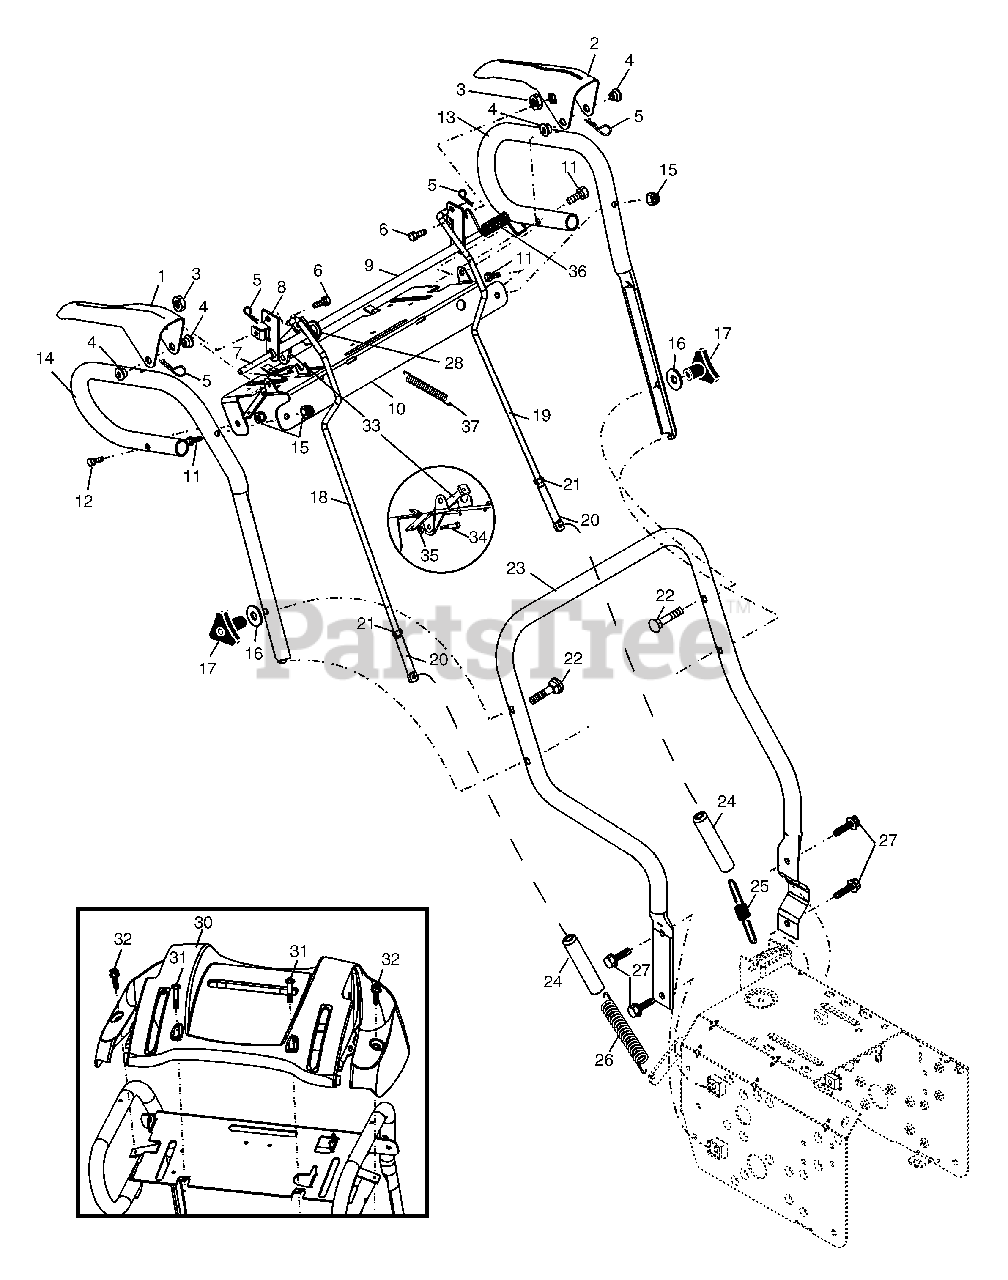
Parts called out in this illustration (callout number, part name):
1	Lever, Auger Control, RH
2	Lever, Traction Drive Control, LH
3	Nut, Cage 1/4-20
4	Bushing, Flange
5	Retainer, Hairpin
6	Screw, Hex Head 1/4-20 x 3/4
7	Rod, Interlock
8	Tube Assembly, Interlock, RH
9	Tube Assembly, Interlock, LH
10	Panel, Control
11	Screw, Hex Head 5/16-18 x 1-1/2
12	Screw, Hex Head 5/16-18 x 1-3/4
13	Handle Tube, LH
14	Handle Tube, RH
15	Nut, Lock 5/16-18
16	Washer, Flat 3/8
17	Knob, Handle
18	Rod, Auger Control
19	Rod, Traction Control
20	End, Control Rod
21	Nut, Hex, Jam 5/16-18
22	Bolt, Carriage 3/8-16 x 2-1/4
23	Handle Tube, Lower
24	Sleeve, Spring
25	Spring, Traction Drive
26	Spring, Auger Control
27	Screw, Hex Head 3/8-16 x 1
28	Clip, Panel
30	Console, Panel
31	Screw, Hex Head, Tapping #10-24 x 1-1/4
32	Screw, Hex Head, Tapping #10-24 x 1/2
33	Latch, Interlock
34	Bolt, Shoulder
35	Nut, Lock 1/4-20
36	Spring, Torsion
37	Spring, Interlock
38	Bezel, Light
39	Light
40	Wiring Harness, Light
